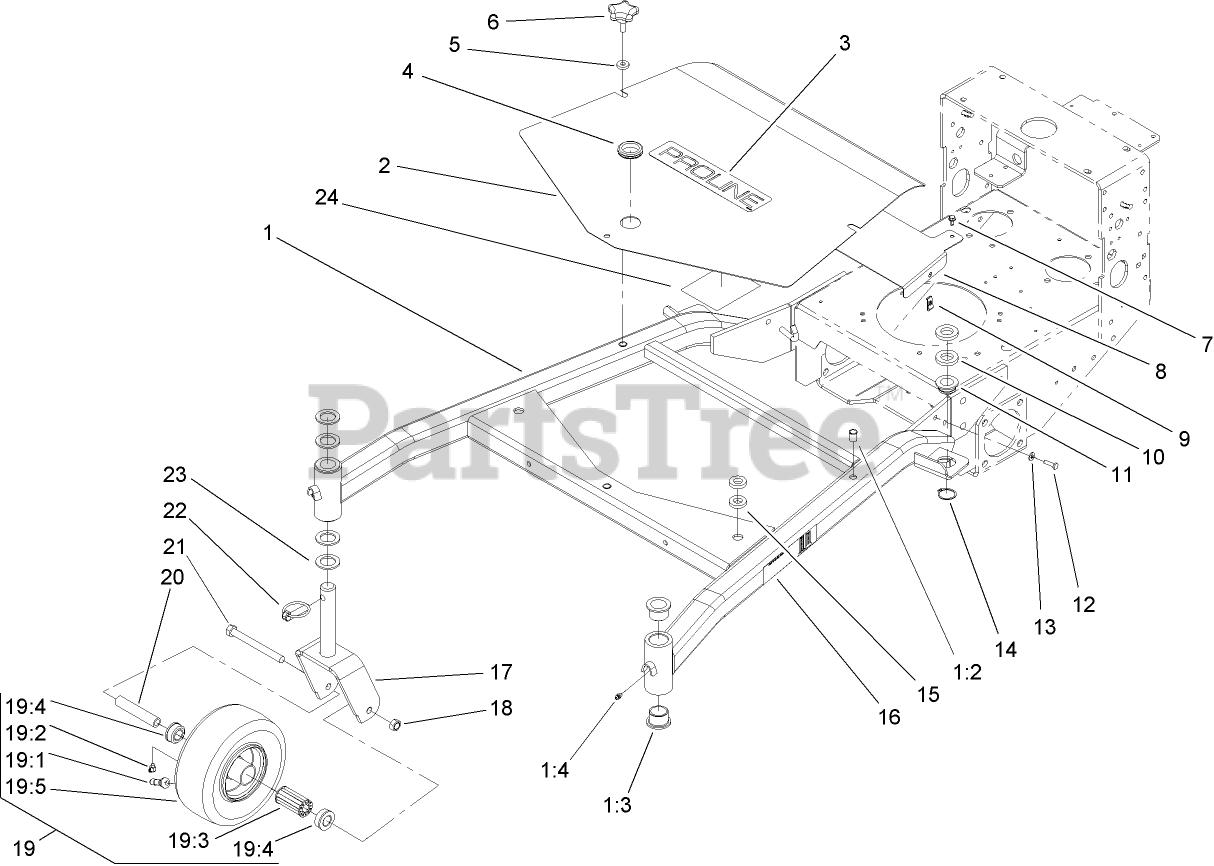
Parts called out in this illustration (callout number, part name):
1	CARRIER FRAME ASM
1:2	INSERT-NUT
1:3	BUSHING
1:4	FITTING-GREASE
2	COVER-FRAME, CARRIER
4	GROMMET-RUBBER
5	WASHER-RUBBER
7	SCREW
8	SHIELD-HEAT
9	NUT-SPEED
10	SPACER-SUPPORT, DECK
11	BUSHING-DECK
12	SCREW-HH
13	WASHER-FLAT
14	RING-RETAINING
15	SPACER
16	DECAL-HOC
17	FORK-CASTOR
18	NUT-HEX
19	CASTER WHEEL ASM
19:1	STEM-VALVE
19:2	FITTING-LUBE, 45 DEG
19:3	BEARING
19:4	BEARING-OUTSIDE
19:5	TIRE-TUBELESS
20	BUSHING-SPANNER
21	SCREW-HH
22	PIN-LYNCH
23	WASHER-THRUST
24	DECAL-SERVICE, GEAR (TBAR)
24	DECAL-SERVICE, HYDRO (TBAR)
24	DECAL-SERVICE, GEAR (PISTOL GRIP)
24	DECAL-SERVICE, HYDRO (PISTOL GRIP)
